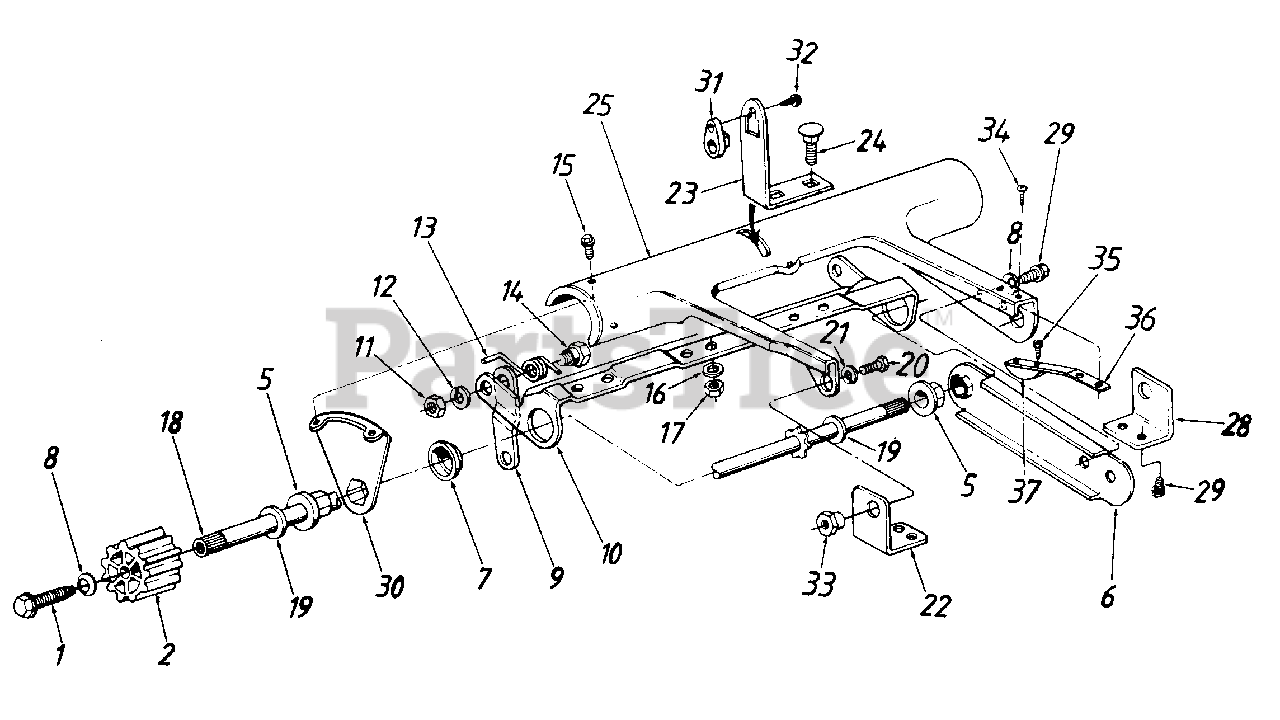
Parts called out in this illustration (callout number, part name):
1	Hex Wash. Hd. Tap Scr. 1/4-20 x .75" Lg.
2	Wheel Drive Pinion-Half
5	Hex Flange Brg. .504" I.D.
8	Bell-Wash. .265" I.D. x .75" O.D.
11	Hex Nut 5/16-18 Thd.
12	L-Wash. 5/16" I.D.
13	Torsion Spring-R.H.
14	Shoulder Bolt .437" Dia.
15	Hex L-Hd. AB-Tap Scr. 1/4" x .62" Lg.
16	L-Wash. 1/4" I.D.
17	Hex Nut 1/4-20 Thd.
18	Drive Shaft Ass'y.
19	Fl-Wash. .531" I.D. x .93" O.D.
20	Hex Bolt 3/8-16 x .5" Lg.
21	L-Wash. 3/8" I.D.
32	Hex B-Tap Scr. #10 x .44" Lg.
33	Shld. Nut .625" Dia. x 165n
34	Truss Mach. B-Tap Scr. #10 x .5" Lg.
35	Hex B-Tap Scr. #10 x 3/8" Lg.
36	Cantilever Spring
37	Chain Tensioner
